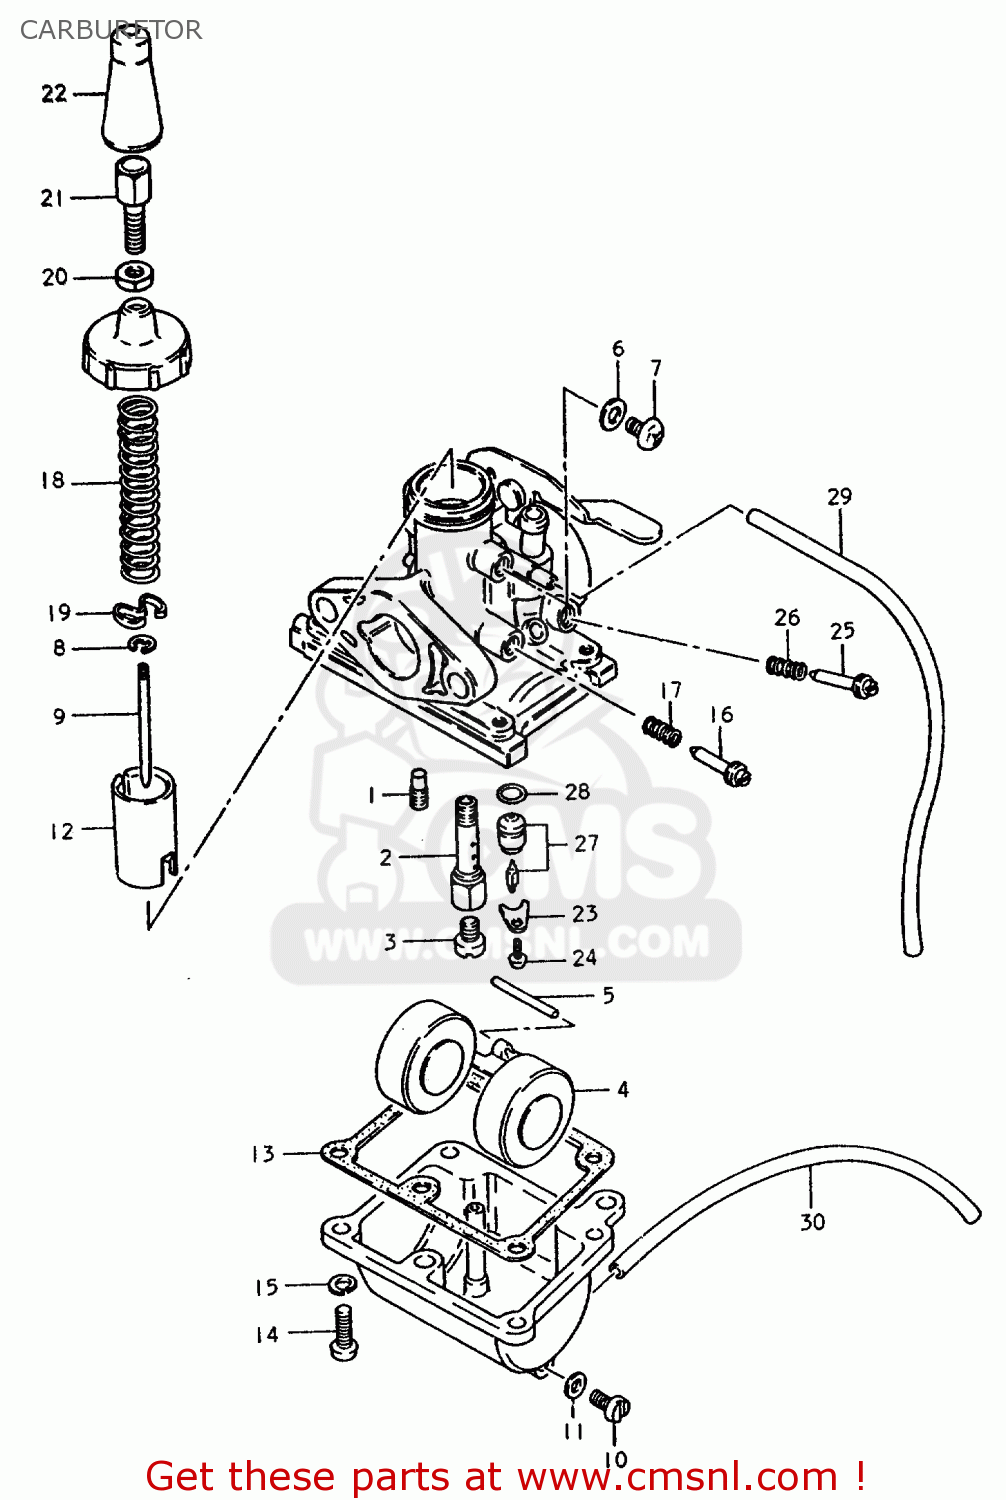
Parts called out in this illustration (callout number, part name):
1	JET,PILOT
2	JET, NEEDLE (E-7)
3	JET,MAIN(70)
4	FLOAT
5	PIN,FLOAT
6	RING
7	SCREW
8	CLIP,NEEDLE
9	NEEDLE,JET
10	PLUG
11	GASKET,DRAIN,PLUG (NAS)
12	VALVE,THROTTLE
13	GASKET,FLOAT CHAMBER (NAS)
14	SCREW
15	LOCK WASHER
16	SCREW,THROTTLE STOP
17	SPRING
18	SPRING,THROTTLE VALVE RETURN
19	PLATE,THROTTLE VALVE
20	NUT
21	ADJUSTER,CABLE
22	CAP
23	PLATE,NEEDLE VALVE FITING
24	SCREW
25	SCREW,AIR
26	SPRING
27	VALVE ASSY,NEEDLE
28	O-RING,NEEDLE VALVE
29	HOSE
30	HOSE
